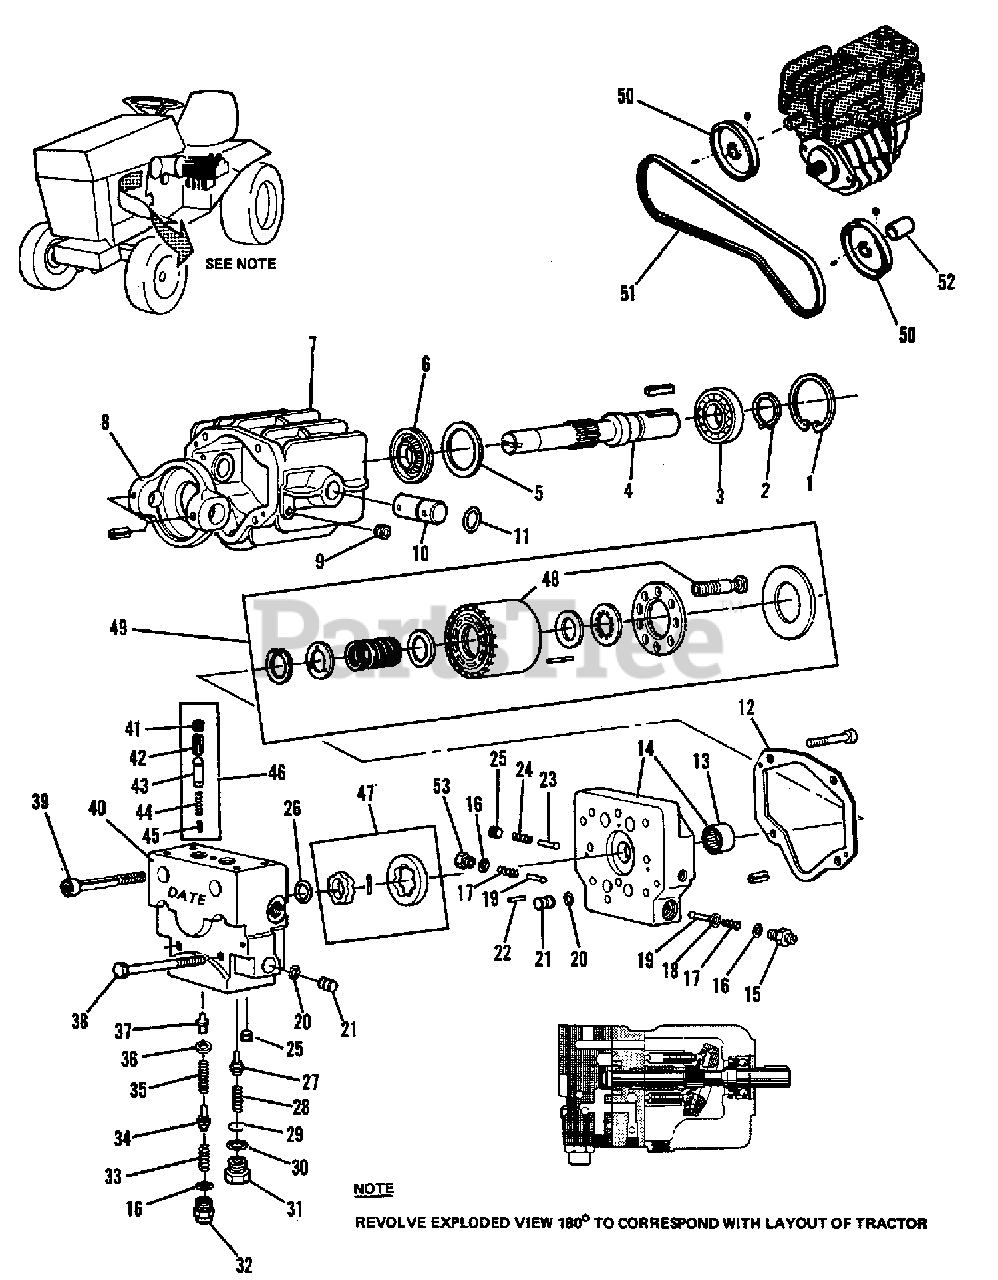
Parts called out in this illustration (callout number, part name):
1	RING, Snap
2	RING, Snap
3	BEARING, Ball
4	SHAFT, Pump
5	SPACER, Bearing
6	SEAL, Shaft
7	HOUSING, Pump
8	PIN, Dowel
10	ROD, Control
12	GASKET, Valve Plate
13	BEARING, Needle
14	PLATE ASSEMBLY, Valve (Includes Item 13)
14	PIN, Dowel
15	CONNECTOR
23	VALVE, Ball Check
29	SHIM (Use As Required)
34	PIN ASSEMBLY
36	SEAT, Spring
37	POPPET ASSEMBLY
40	BLOCK, Transfer
42	GUIDE, Spring
43	VALVE, Check
46	VALVE REPAIR KIT (Includes 41 to 45)
47	GEROTOR KIT, (Includes KEY)
47	KEY, Gerotor
48	CYLINDER KIT, (Includes PISTONS)
49	PUMP REPAIR KIT
50	PULLEY, Drive (Prior S/N 15101001, 15201001, 15301001, 15401010, 15501031, 15601001, 15701001 & 15801077)
50	PULLEY, Drive (Effective S/N 15101001, 15201001, 15301001, 15401010, 15501031, 15601001, 15701001 & 15801077)
51	BELT, Hydrostatic Drive
52	SPACER, Pulley (Prior S/N 15101001, 15201001, 15301001, 15401010, 15501031, 15601001, 15701001 & 15801077)
52	SPACER, Pulley (Effective S/N 15101001, 15201001, 15301001, 15401010, 15501031, 15601001, 15701001 & 15801077)
